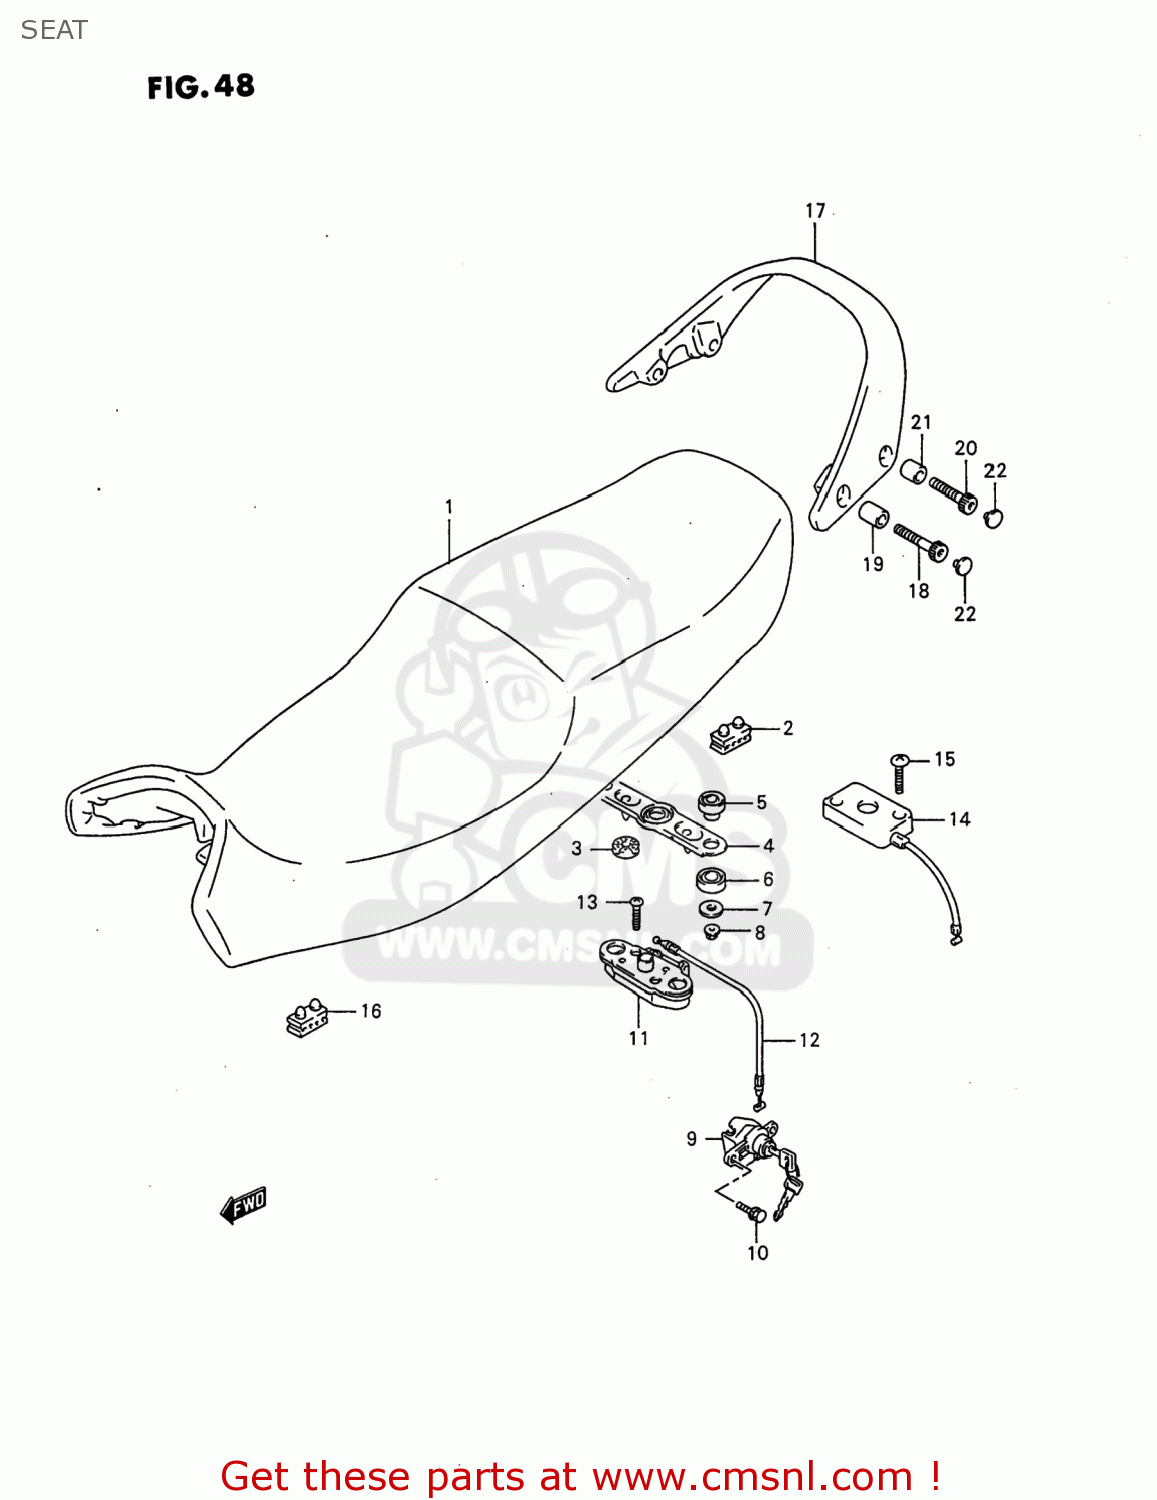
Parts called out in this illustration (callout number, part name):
1	SEAT ASSY
2	CUSHION,SEAT(40X20X15)
3	CUSHION,SEAT LOCK(10X22X6)
4	STRIKER,SEAT LOCK
5	CUSHION
6	CUSHION
7	WASHER
8	NUT
9	LOCK SET,SEAT
10	BOLT
11	BRACKET,SEAT SUPPORT,RIGHT
12	CABLE,SEAT LOCK
13	SCREW
14	BRACKET,SEAT SUPPORT FR
15	SCREW
16	CUSHION,SEAT(40X20X15)
17	HANDLE,PILLION RIDER
18	BOLT
19	SPACER(8.1X16X17)
20	BOLT
21	SPACER(10.2X16X12)
22	CAP(OD:14.5)
